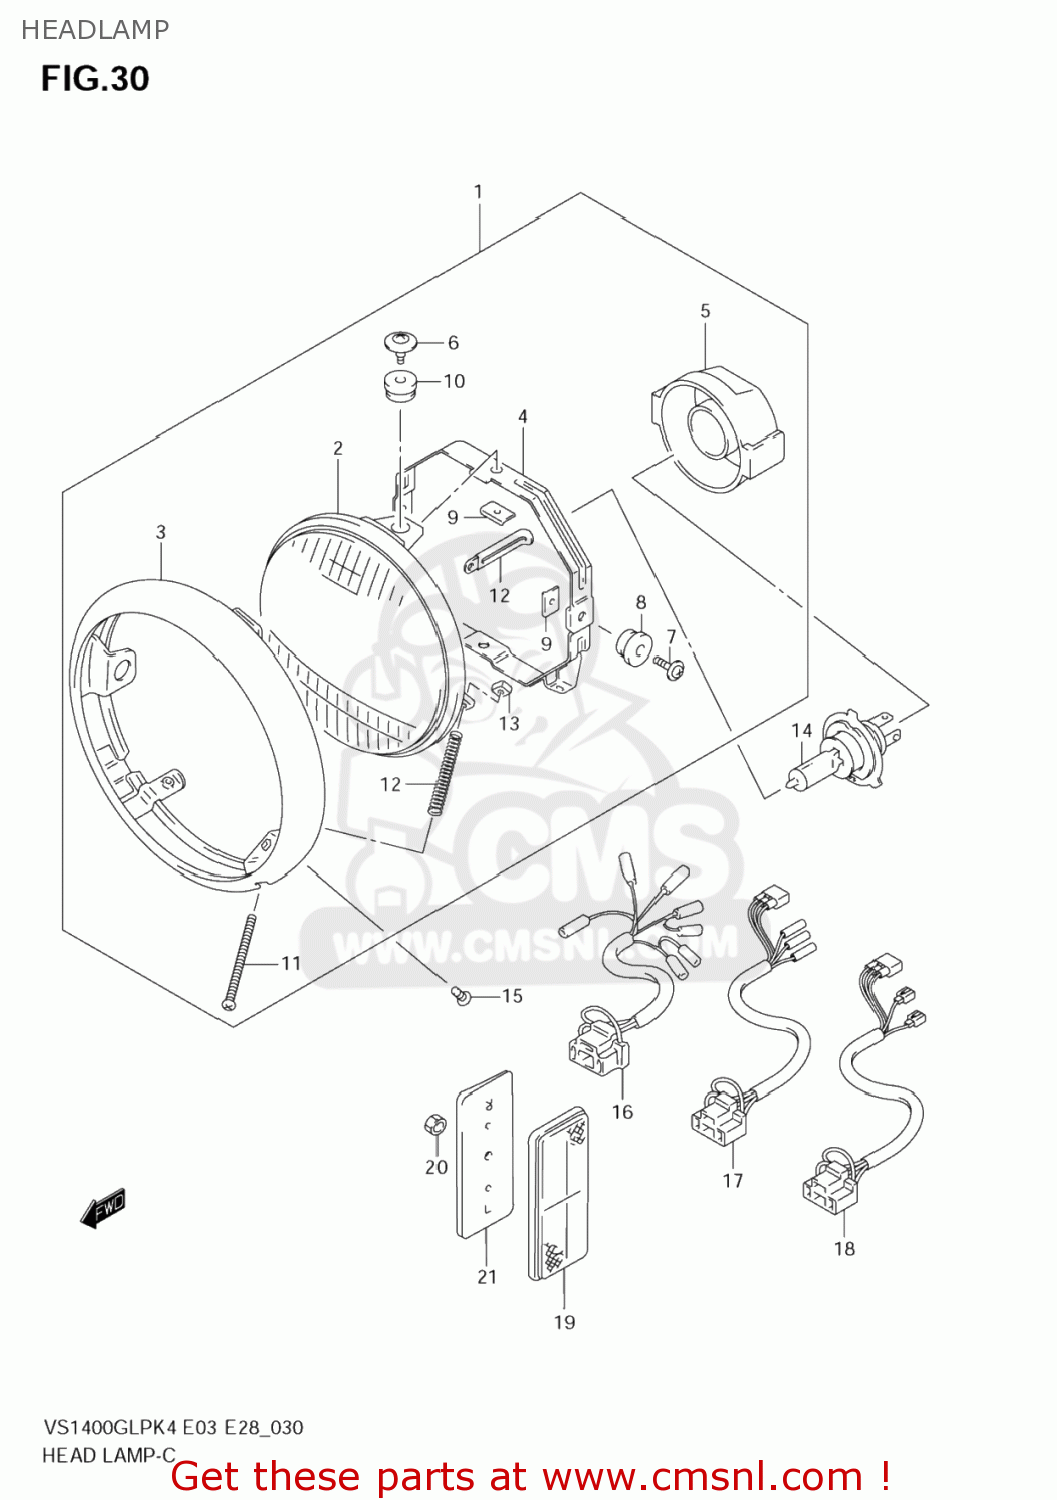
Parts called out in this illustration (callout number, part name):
1	HEADLAMP ASSY
2	UNIT,LAMP
3	RIM
4	RING,MOUNTING
5	COVER
6	SCREW
7	SCREW,MOUNTING
8	CUSHION
9	NUT
10	CUSHION
11	SCREW,ADJUSTING(4X50)
12	SPRING
13	NUT,HEADLAMP ADJUST
14	BULB(12V60/55W,H4)
15	SCREW(5X12)
16	WIRE,HEADLAMP LEAD
17	WIRE,HEADLAMP LEAD
18	WIRE,HEADLAMP LEAD
19	REFLEX REFLECTOR,FR SIDE
20	NUT
21	SPACER,FR SIDE RR
